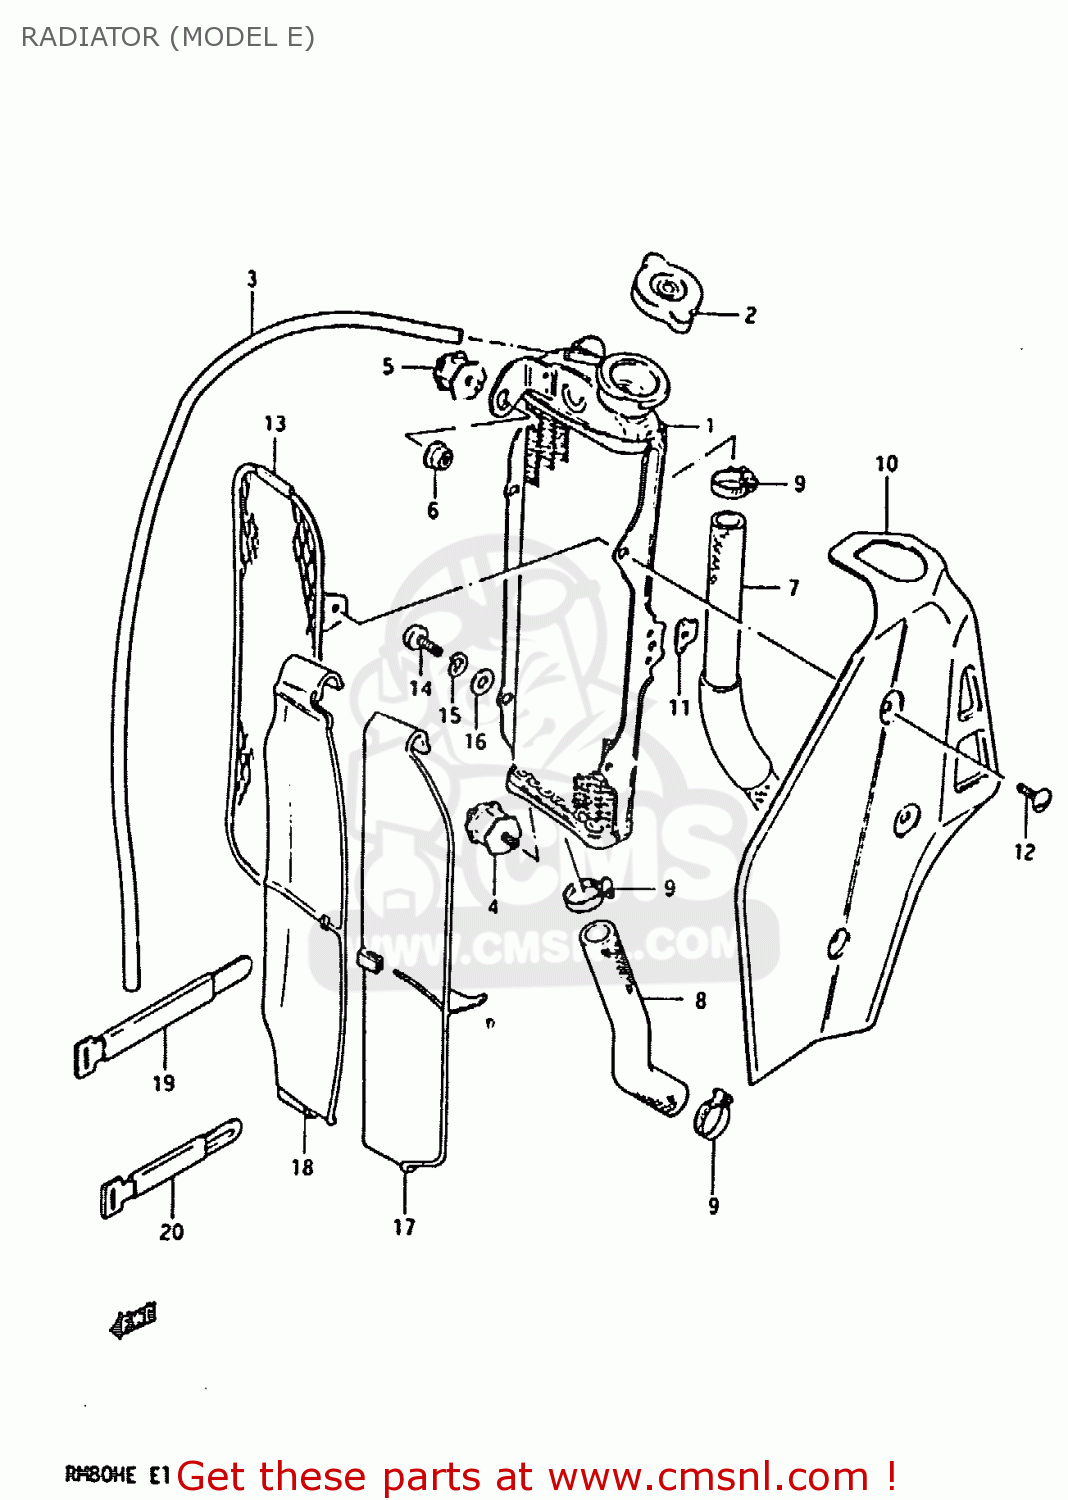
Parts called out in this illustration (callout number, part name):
1	RADIATOR ASSEMBLY,WATER
2	CAP,RADIATOR 1.1
3	HOSE
4	CUSHION,RADIATOR
5	CUSHION
6	NUT
7	HOSE, INLET
8	HOSE, OUTLET
9	CLAMP
10	COVER,RADIATOR
11	PLATE,RADIATOR COVER FITING
12	SCREW(6X14)
13	BUMPER,RADIATOR
14	SCREW
15	LOCK WASHER
16	WASHER
17	LOUVER,RADIATOR
18	LOUVER,RADIATOR
19	CLAMP
20	CLAMP
